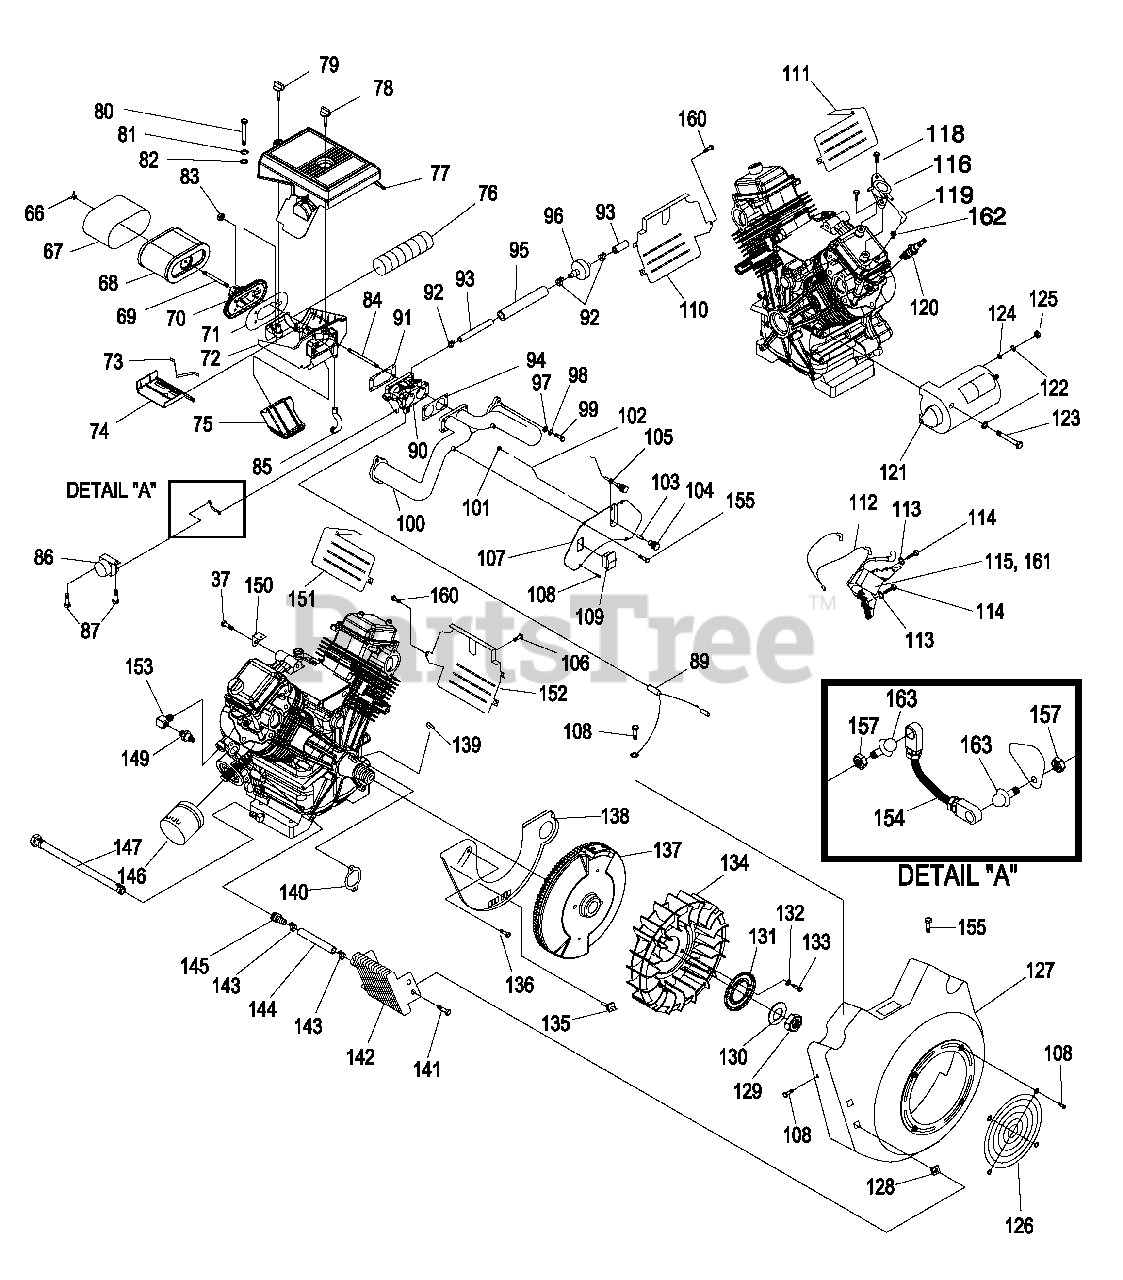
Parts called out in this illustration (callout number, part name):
66	WINGNUT, AIRBOX
67	PRECLEANER, AIR
68	ELEMENT, AIR CLEANER
69	STUD M6-1.0 X 73
70	ADAPTOR, SPIT BACK
71	GASKET, SPITBACK
72	BASE, AIRBOX
73	SPRING, WINTER/SUMMER VALVE
74	VALVE, SUMMER / WINTER
75	SNORKEL, AIR INTAKE
76	TUBE, HEAT RISER 50.8 I.D.
77	COVER, AIRBOX
78	KNOB, AIRBOX 17mm
79	KNOB, AIRBOX 95MM
80	SCREW HHC M6-1.0 X 35
81	WASHER LOCK M6-1/4
82	WASHER FLAT 1/4
83	NUT, HEX FLANGE WHIZ M6-1.0
84	STUD, METRIC
85	HOSE, BREATHER
86	CONTROLLER ASSEMBLY
87	SCREW HHTT M5-0.8 X 10
89	ASSEMBLY, WIRE
90	CARBURETOR (GT-990)
91	GASKET, CARB TO SPACER (GT-990)
92	CLAMP HOSE BAND 1/4
93	HOSE 1/4 ID
94	GASKET, MANIFOLD TO CARB (GT-990)
95	SLEEVING, FLEXO HW 3/4 3"
96	FILTER, FUEL
97	WASHER FLAT M8
98	WASHER LOCK M8
99	SCREW SHC M8-1.25 X 30
100	MANIFOLD, INTAKE
101	NUT HEX M3-0.5
102	ROD, SUMMER / WINTER VALVE
103	BUSHING, MINI CONTROL PANEL
104	KNOB, CONTROL SUMMER / WINTER
105	CHOKE ASSEMBLY
106	SCREW TAPTITE M5-0.8 X 8 ZP
107	PANEL, CONTROL FACE PLATE
108	SCREW TAPTITE M6-1.0X 10 YELLOW CHROME
109	SWITCH ROCKER
110	WRAPPER, LOWER CYLINDER 2
111	WRAPPER, UPPER CYLINDER 2
112	ASSEMBLY, GROUND WIRE
113	WASHER LOCK M6-1/4
114	SCREW TAPTITE M6-1.0 X 25 ZINC
115	ASSY, IGN COIL W/DIODE NO ADV
116	PUMP, IMPULSE
118	SCREW, HHFCS M6-1.0 X 16 G8.8
119	ELBOW, RUBBER 90 DEG. GASOLINE
120	SPARKPLUG, CHAMPION RC14YC
121	STARTER, DELCO REMY SD80
122	WASHER LOCK M8-5/16
123	SCREW HHC M8-1.25 X 85 G8.8
124	WASHER, FLAT M8
125	NUT, HEX M8-1.25 YELLOW ZINC
126	GUARD,FAN
127	HOUSING, BLOWER GAS COOLER
128	NUT, GROMMET 1/4 PLUG
129	NUT,HEX M24
130	WASHER, M24
131	PLATE, FAN
132	WASHER SHAKEPROOF INT M8 SS
133	SCREW HHC M8-1.25 X 12 G8.8
134	FAN, NYLON
135	ASSY,GROUND WIRE CONNECTOR
136	SCREW TAPTITE M6-1X10 YELLOW CHROME
137	FLYWHEEL ASSEMBLY
138	PLATE, BACKING GT990 W/OIL COOL
139	KEY, WOODRFF 4 X 19D
140	GASKET, MANIFOLD / PORT
141	PLASTITE,1/4-15 X 3/4
142	COOLER, OIL
143	CLAMP, HOSE OETIKER 16.5mm
144	HOSE 3/8" 300PSI 6" LONG OIL
145	BARBED STR 1/4NPT X 3/8
146	OIL FILTER
147	ASSY OIL DRAIN HOSE
149	SWITCH, OIL PRESS
150	BRACKET, AIRBOX SUPPORT
151	WRAPPER, UPPER CYLINDER 1
152	WRAPPER, LOWER CYLINDER 1
153	BRASS ST ELBOW 1/4 NPT
154	ASSY, ROD, GOV. STEPPER MOTOR
155	SCREW HHHC M6-1.0 X12
157	NUT, LOCK HEX M3-0.5 (GT-990)
160	SCREW HHFC M6-1.0 X 10mm
161	ASSY, IGN COIL W/DIODE NO ADV
162	CLAMP, HOSE BAND GREEN
163	BALL STUD
